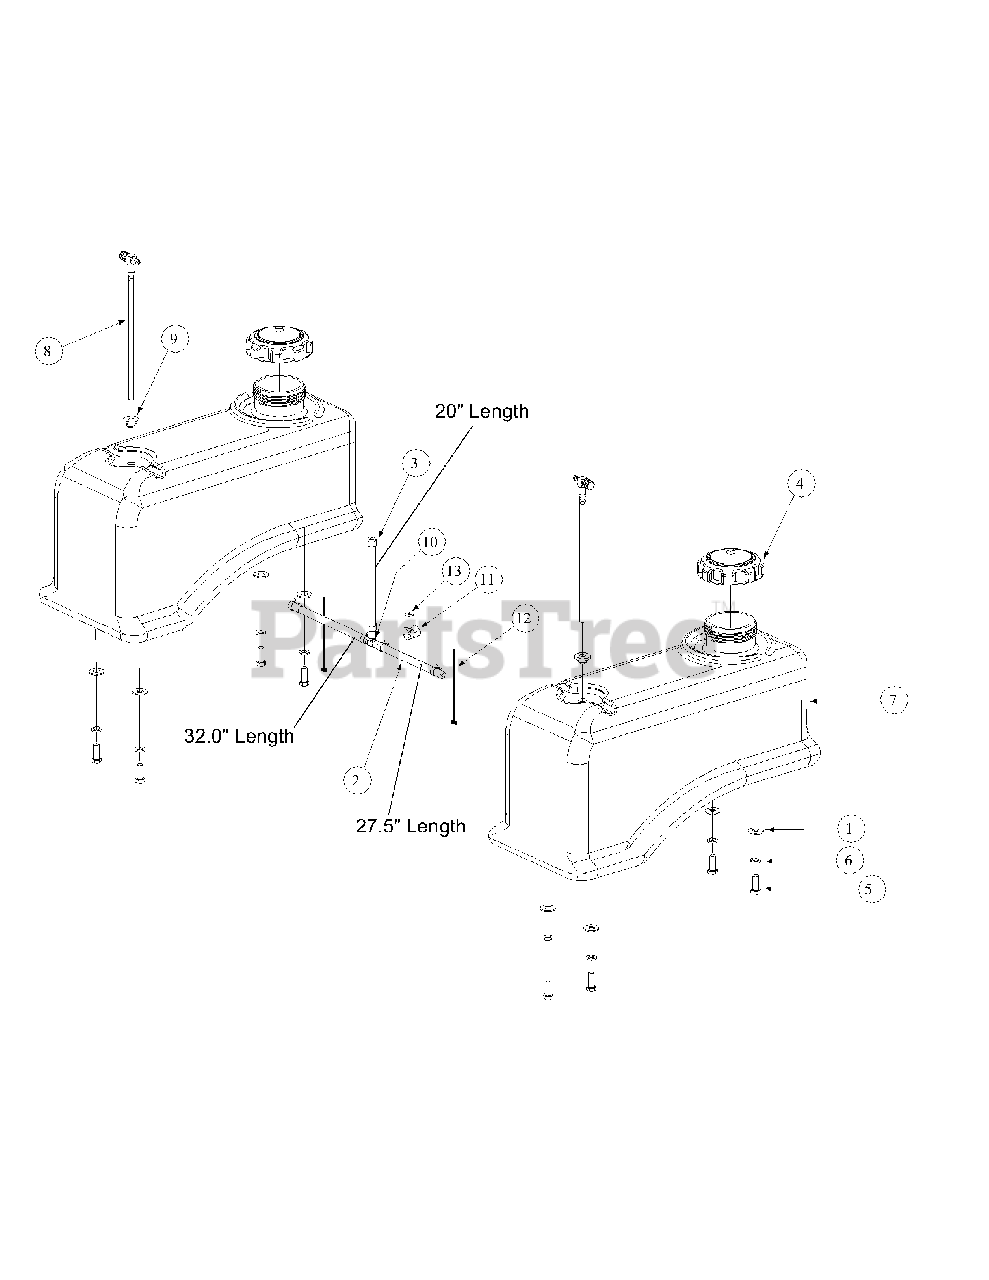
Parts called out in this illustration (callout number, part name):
1	Flat Washer, .406 ID, 1.0 OD, .105
3	Clamp, Union
4	Fuel Cap, 3.5
5	Hex, Cap Screw, 3/8-16, .88
6	Lock Washer, 3/8
7	Fuel Tank
8	Fuel Fitting
9	Fuel Tank Grommet
10	Tee Fitting, Fuel
12	Cable Tie
13	Flatwasher 1/4 x .630 x .0515
